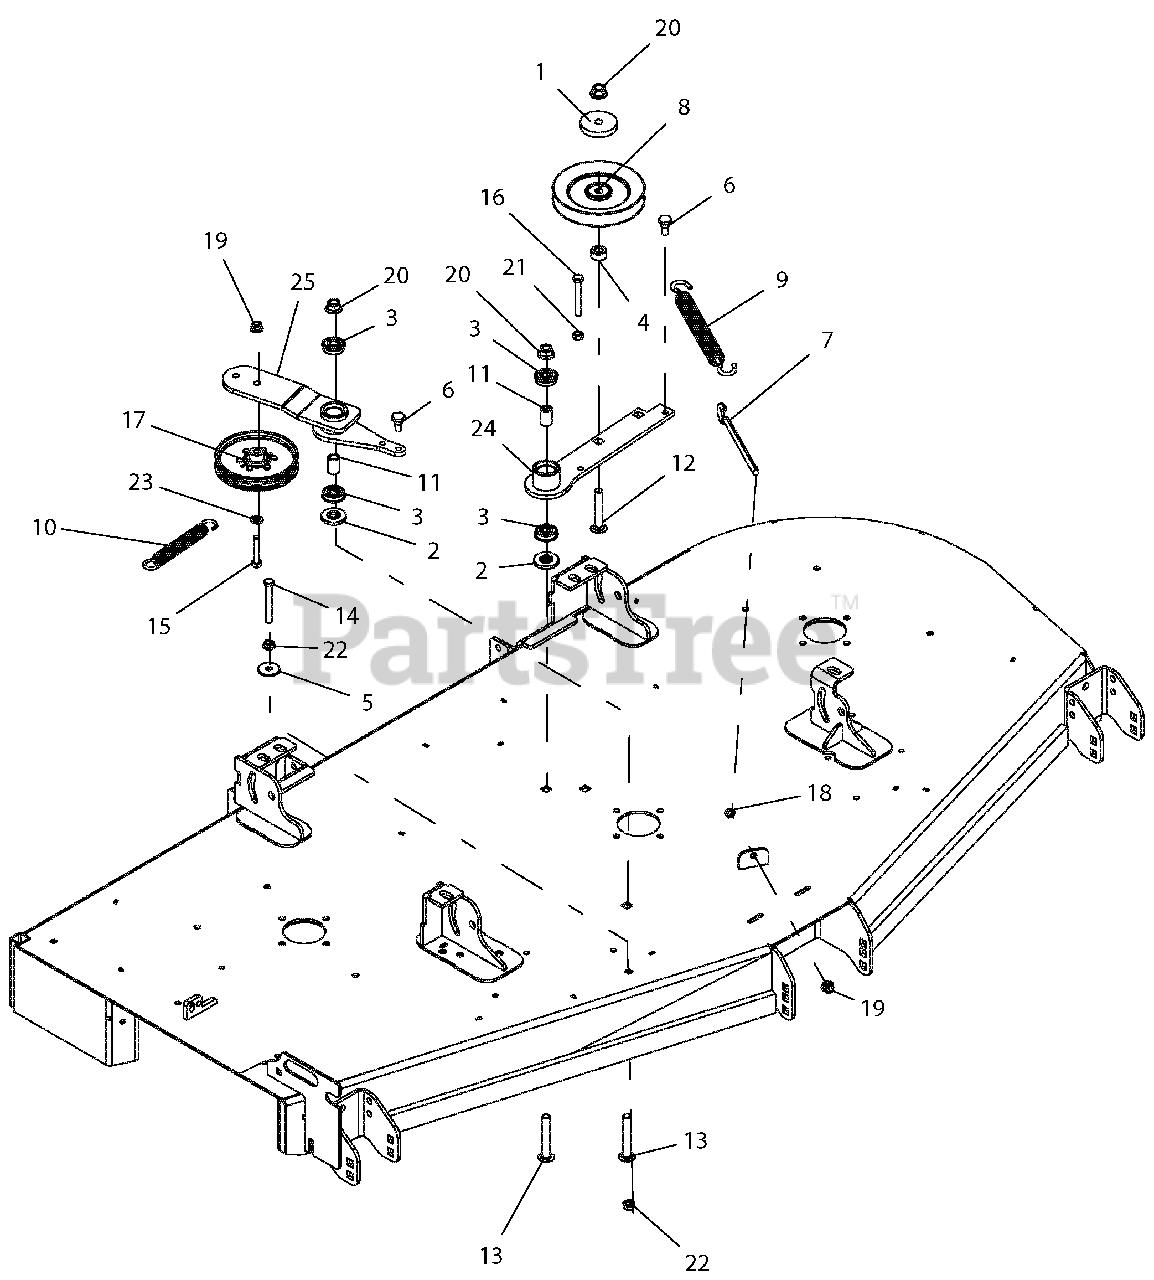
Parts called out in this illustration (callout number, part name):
1	CAP, IDLER BEARING SEALING
2	SPACER, IDLER ARM
3	BRG, BALL .501 X 1.38 X .438 SEALED
4	BSHG, SPCR .502 X .997.50 PM
5	WSHR-FL-STL .406X1.375X.135 YZ
6	BLT, SHLDR EP .38-16X.30 HEX YZ
7	BOLT, .38-16X6.00 .62 DIA EYE
8	SHEAVE, .50" ID X 6.00" OD V-IDLER
9	SPRG, EXTENSION
10	SPRG, EXTENSION
11	SPACER, .510 X .750 X 1.148
12	BLT-RDHDSQNK .50-13X3.00 G5 Y
13	BLT-RDHDSQSHNK .50-13X3.25 YWZC
14	BLT-HEX .38-16X3.00 GR5 YWZC
15	BLT-HEX .38-16X2.00 GR5 YWZC
16	BLT-HEX .38-16X2.75 GR5 YWZC
17	PULLEY, FLAT IDLER .500 X .375 W/BRG
18	NUT, JAM .375-16 YWZC
19	NUT-LK-NYL-FLG .38-16 YWZC
20	NUT-LK-NYL-FLG .50-13 YWZC
21	NUT-HEX .38-16 YWZC
22	@NUT-SPNLK-FLG .375-16 YWZC
23	WSHR-FL-STL.406X.812X.065 YWZ
24	WLDMT, DECK PTO IDLER ARM-BLACK
25	WLDMT, DECK RH IDLER ARM
